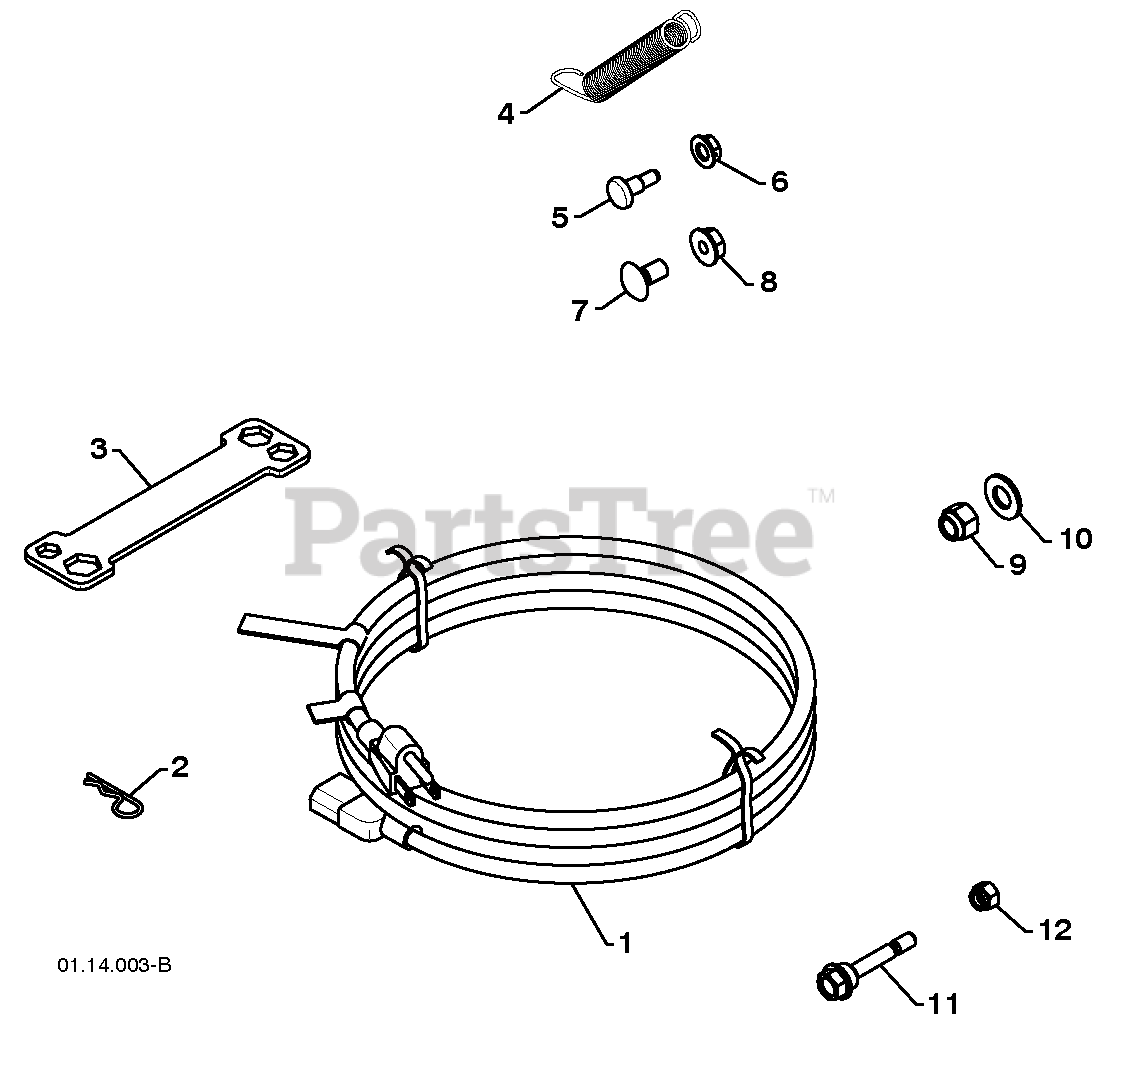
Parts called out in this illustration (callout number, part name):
1	POWER CORD
2	RETAINER PIN
3	WRENCH
4	REMOTE SPRING
5	SHOULDER BOLT 1/4-20
6	LOCKNUT 1/4-20
7	CARRIAGE BOLT 5/16-18 X 5/8
8	LOCKNUT 5/16-18
9	LOCKNUT 3/8-16
10	WASHER 3/8
11	SHEAR BOLT 1/4-20 X 1-13/16
12	LOCKNUT 1/4-20
